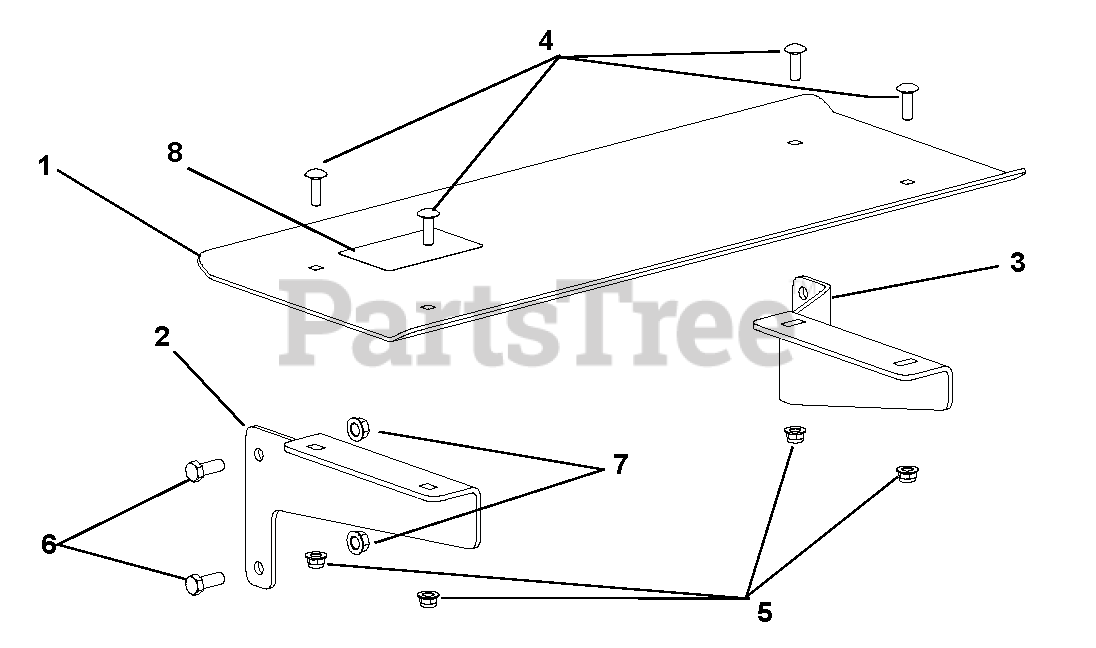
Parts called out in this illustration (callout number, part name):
1	TABLE, WORK - LOG SPLITTER
2	BRKT, FRONT - WORK TABLE
3	BRKT, REAR - WORK TABLE
4	@BLT-RHDSSQNK .31-18X1.00 G5YZ
5	@NUT-LK-NYL-FLG .31-18 YWZC
6	@BLT-HEX .38-16X1.00 GR5 YWZC
7	@NUT-LK-TOP-FLG .38-16 YWZC
8	DECAL,SPLITTER TABLE
